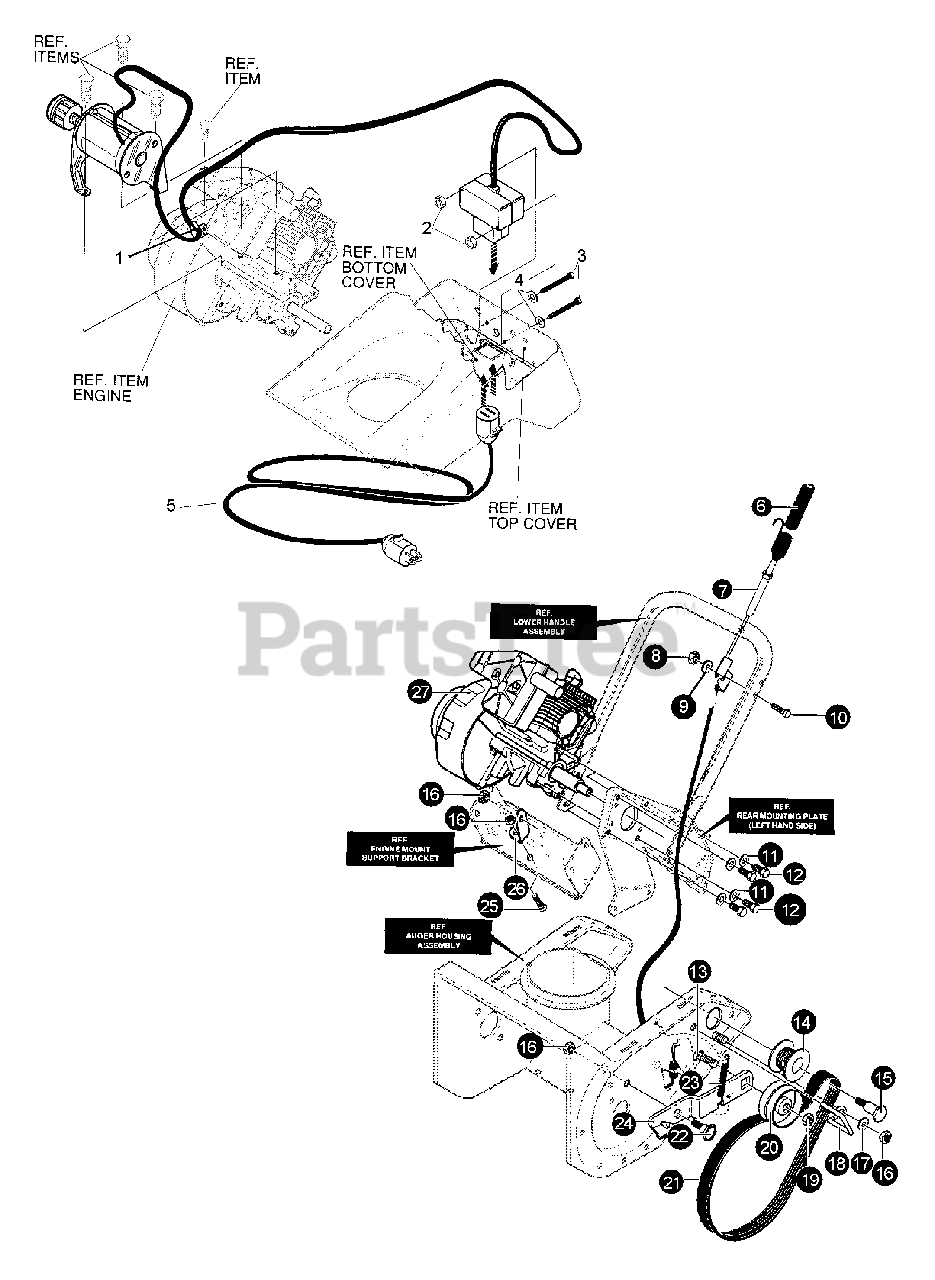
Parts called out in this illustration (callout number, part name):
1	RETAINER, WIRE
2	NUT - 8-32 -- KEPS
3	SCREW - 8-32×3.00"
4	WASHER - 0.188×0.38×0.040"
5	CORD, EXTENSION 10 FEET
7	CABLE, DRIVE CONTROL
8	NUT, 1/4"-20
9	WASHER
10	SCREW
11	WASHER
12	SCREW 5/16"-18×0.75
13	BOLT, 3/8-16×1.50 CARRSN
14	PULLEY, 4.5 HP
15	BOLT, SHOULDER 0.625×0.282
16	NUT, 5/16"-18
17	WASHER, FLAT 0.312×0.73×0.065
18	GUIDE, BELT 21"
19	LOCKNUT - 3/8-16
20	PULLEY, IDLER BB 1.88 OD
21	BELT, 10 RIB
22	BOLT, 0.500×0.177 HHSH 5/16-18
23	SPRING, IDLER BRAKE
24	BRACKET, IDLER ARM
25	SCREW - 5/16-18 X0.50" -- HEX HEAD CAP
26	SUPPORT, ENGINE
